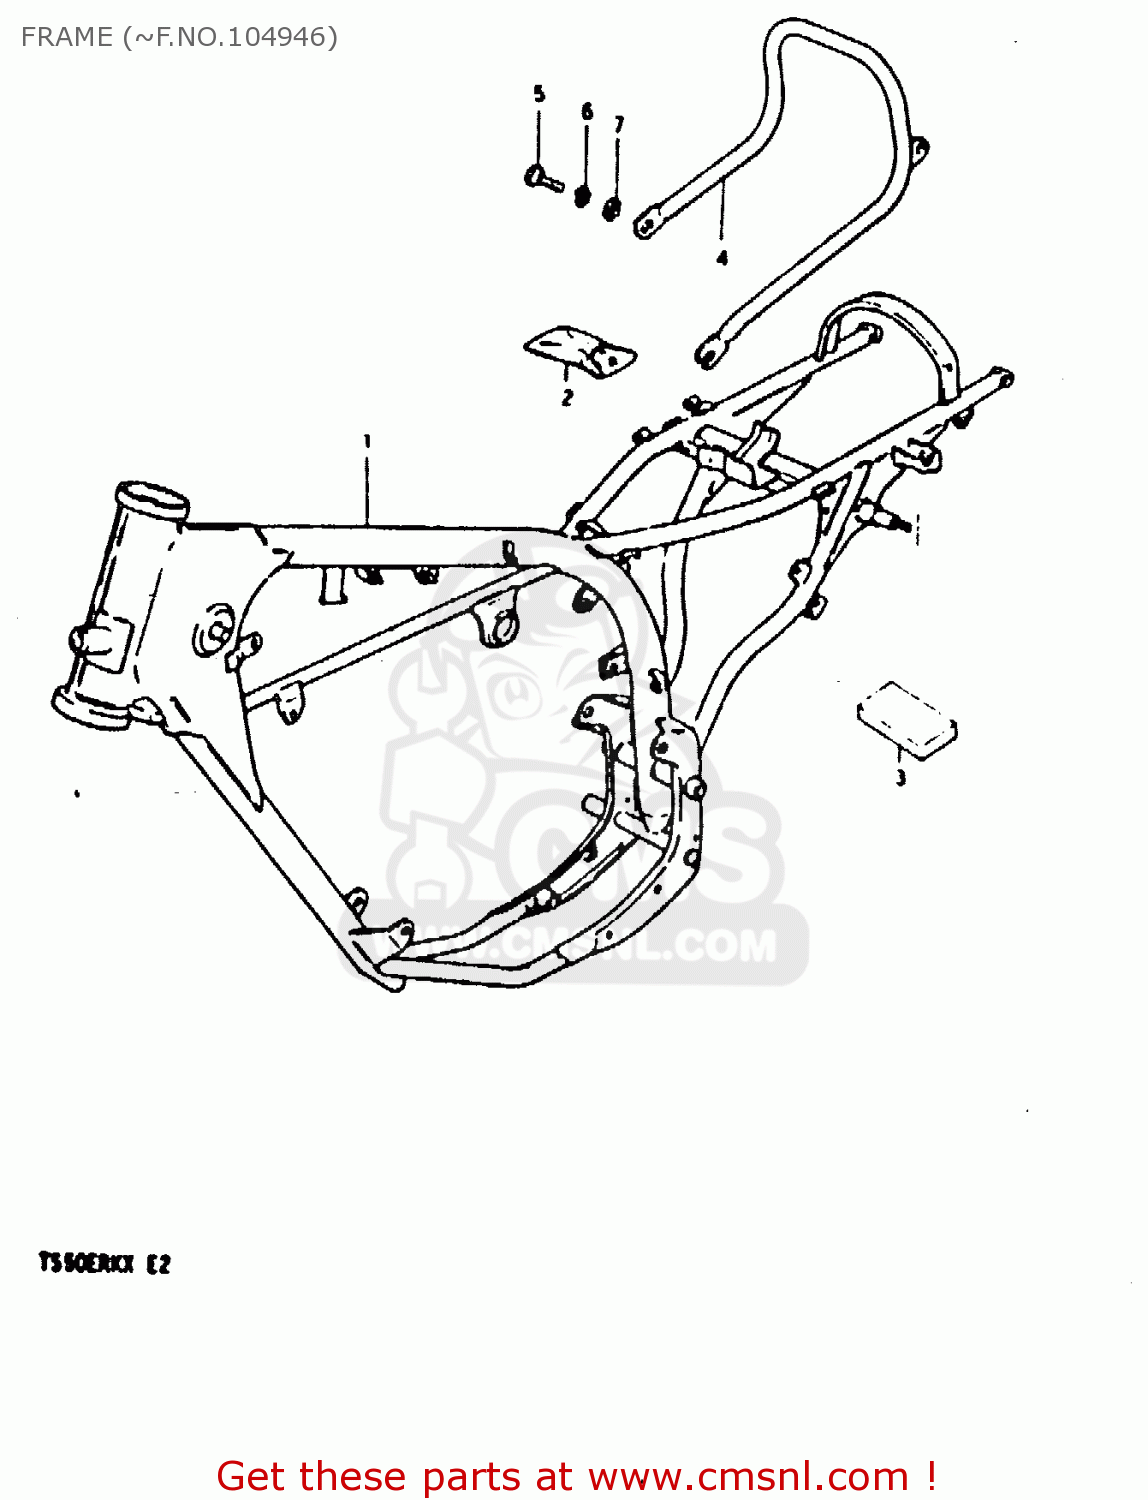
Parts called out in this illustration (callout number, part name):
1	FRAME (BLACK)
2	TOOL SET
3	CUSHION(30X60X10)
